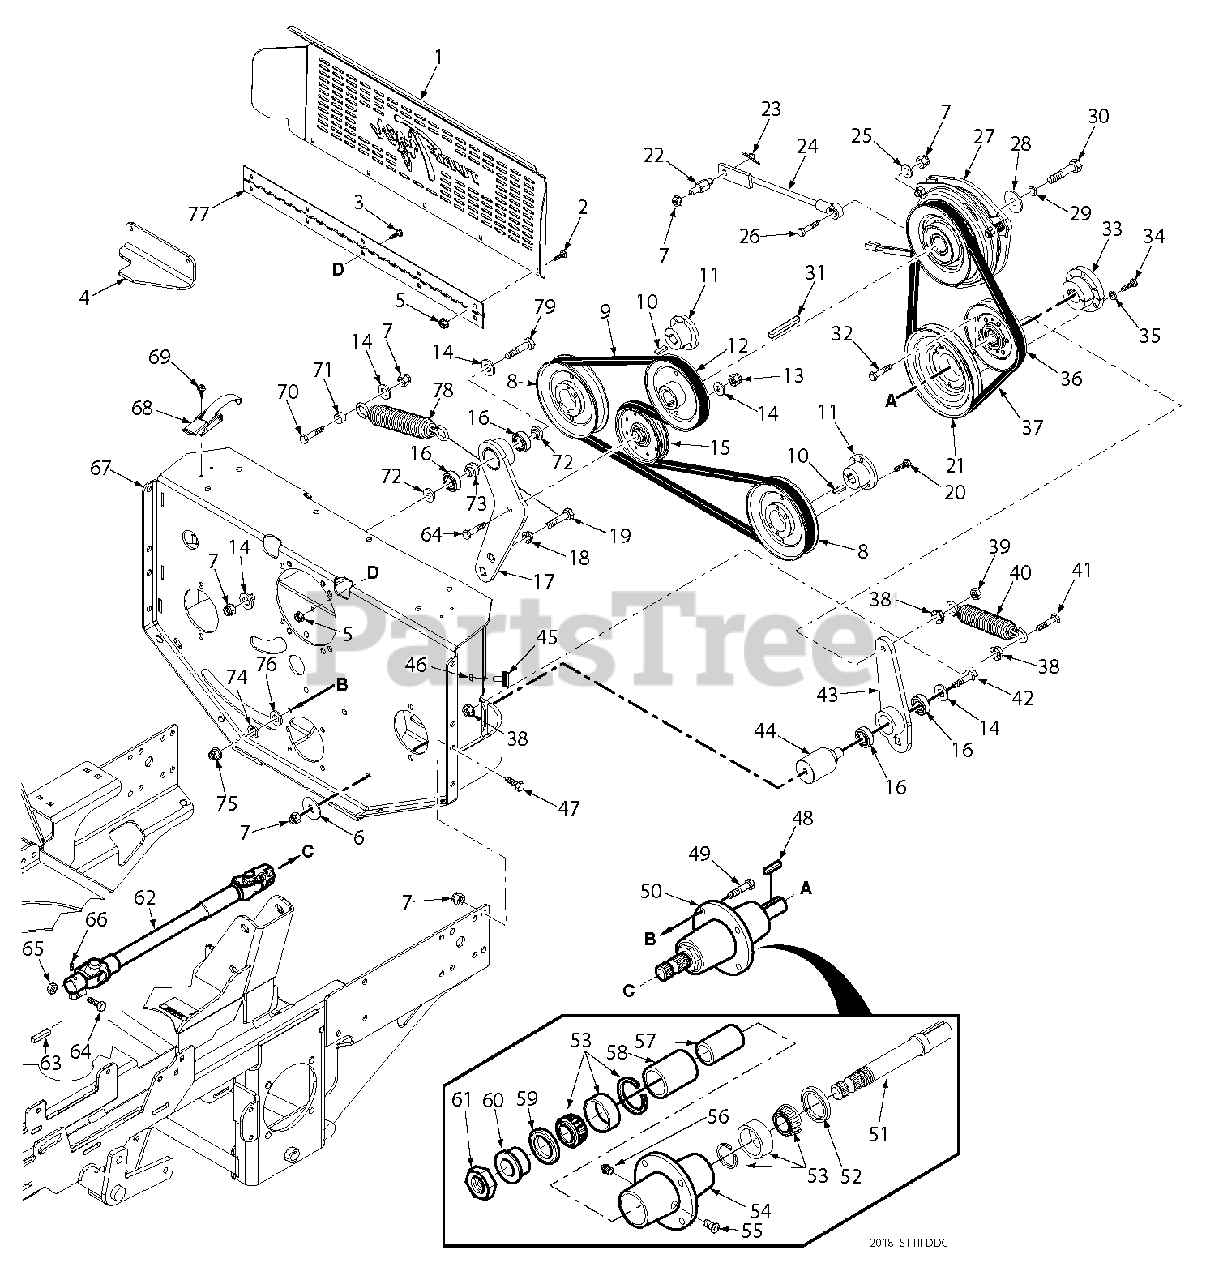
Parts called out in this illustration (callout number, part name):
1	Cover, Rear
2	Bolt, Carriage 1/4-20 x 1/2"
3	Bolt, Carriage 1/4-20 x 3/4"
4	Bracket, Idler Stop
5	Nut, Serrated Flange 1/4-20
6	Flatwasher, 3/8-.406 x 1.50 x 7 Gauge
7	Nut, Elastic Stop 3/8-16
8	Pulley, 5.75 O.D. (Gasoline Engines)
8	Pulley, 6.35 O.D. (Diesel Engine)
9	Belt, STTII Pump Drive (Gasoline Engines)
9	Belt, STTII Pump Drive (Diesel Engine)
10	Key, 5mm x 5mm x 30mm
11	Tapered Hub, 17mm Bore
12	Pulley, 5.67 O.D. (Kawasaki & Kohler Only)
12	Pulley, 5.67 O.D. (35BV & 37BV-EFI Only)
12	Pulley, 5.67 O.D (Kubota Diesel Only)
13	Nut, Center Lock 3/8-16
14	Flatwasher, 3/8-.391 x .938 x .105 HD
15	Pulley, Idler 4"
16	Bearing
17	Idler Arm Assy.
18	Nut, Serrated Flange 1/2-13
19	Bolt, Hex Head 1/2-13 x 2"
20	Bolt, Hex Head 1/4-20 x 1"
21	Pulley, 6.70 O.D.
22	Stud, Anti-Rotation
23	Pin, Rue Cotter
24	Rod Assembly
25	Flatwasher, 3/8-.438 x 1.00 x .083
26	Bolt, Hex Head 3/8-16 x 1-1/4"
27	Clutch Assembly, GT3.5
27	Clutch Assembly, GT3.5 (Diesel Engine)
27	Clutch Assembly, GT5 (35BV & 37BV-EFI)
28	Flatwasher, 7/16-.469 x 1.50 x .1793
29	Lockwasher, 7/16"
30	Bolt, Hex Head 7/16-20 x 2-1/2" (Kohler)
30	Bolt, Hex Head 7/16-20 x 2-1/4" (35 & 37BV)
30	Bolt, Hex Head 7/16-20 x 2-1/4" (Kubota)
30	Bolt, Hex Head M10-1.5 x 50 (Kawasaki)
31	Key, 1/4 x 1/4 x 3-1/4"
32	Bolt, Hex Head 3/8-16 x 2-1/2"
33	Tapered Hub, 1" Bore
34	Bolt, Hex Head 1/4-20 x 1.375 Full Thread
35	Lockwasher, 1/4"
36	Pulley, Idler
37	Belt, Deck Drive
38	Nut, Serrated Flange 3/8-16
39	Nut, Center Lock 3/8-16
40	Spring, PTO (Gasoline Engines)
40	Spring, PTO (Diesel Engine)
41	Bolt, Hex Head 3/8-16 x 1-1/2"
42	Bolt, Hex Head 3/8-16 x 4-1/2"
43	Idler Arm Assy., PTO Drive
44	Pivot, Idler - PTO
45	Bumper, Rubber
46	Nut, Serrated Flange 5/16-18
47	Bolt, Hex Head 3/8-16 x 1"
48	Key, 1/4 x 1/4 x 1-1/2"
49	Bolt, Hex Head 5/16-18 x 1-3/4"
50	Spindle Assy., PTO
51	Shaft, Deck Drive
53	Bearing Assembly, Tapered
54	Spindle Housing
55	Relief Fitting
56	Grease Fitting, 1/4-28
57	Spacer, Inside
58	Spacer, Outside
59	Seal, 2" O.D. x 1.625 Bore
60	Spindle Bushing, Bottom
61	Nut, 1.06 - 18
62	Driveshaft
63	Key, 1/4 x 1/4 x 1"
64	Bolt, Hex Head 3/8-16 x 1-3/4"
65	Nut, Center Lock 3/8-16
66	Set Screw, 3/8-16 x 1/2" Internal Hex
67	Pump Mounting Plate Weldment (Gasoline)
67	Pump Mounting Plate Weldment (Diesel)
68	Latch, Hood
69	Screw, #10-32 x .563 Shakeproof
70	Bolt, Hex Head 3/8-16 x 1-1/2"
71	Spacer, Spring Anchor
72	Spacer, Controls
73	Spacer, Bearing
74	Lockwasher, 5/16"
75	Nut, Elastic Stop 5/16-18
76	Flatwasher, 5/16-.375 x .875 x .083
77	Hinge, Belt Cover
78	Spring Pump Drive
79	Bolt, Hex Head 3/8-16 x 2-3/4"
